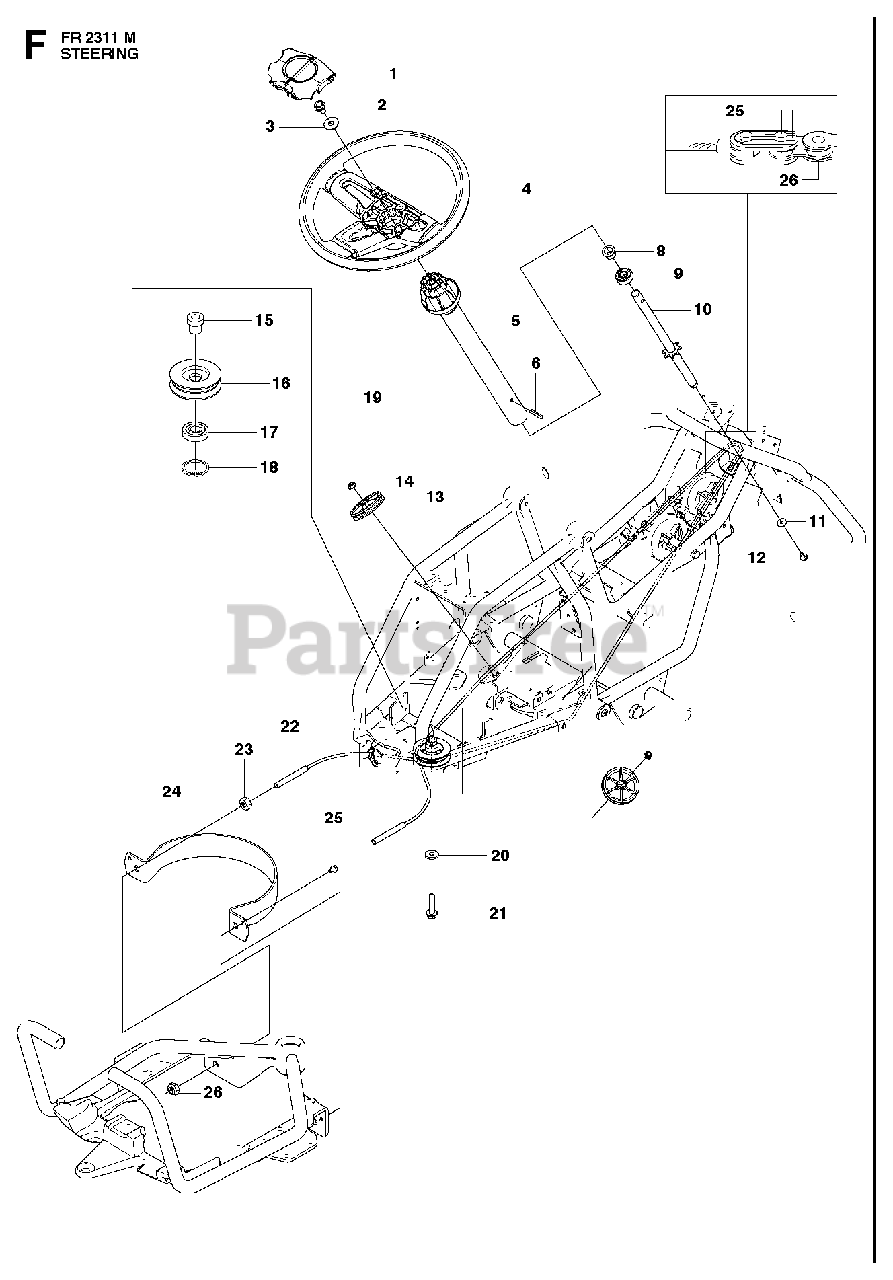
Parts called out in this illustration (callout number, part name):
9	BALL BEARING 6004-2RS1
11	WASHER - 26X6.5X1.6
12	SCREW EHHFM
14	LOCKNUT M6
17	BALL-BEARING 6204-2RS
18	CIRCLIP SGH 47
19	STEERING ASSY
22	WIRE ASSY
26	STEERING CHAIN
